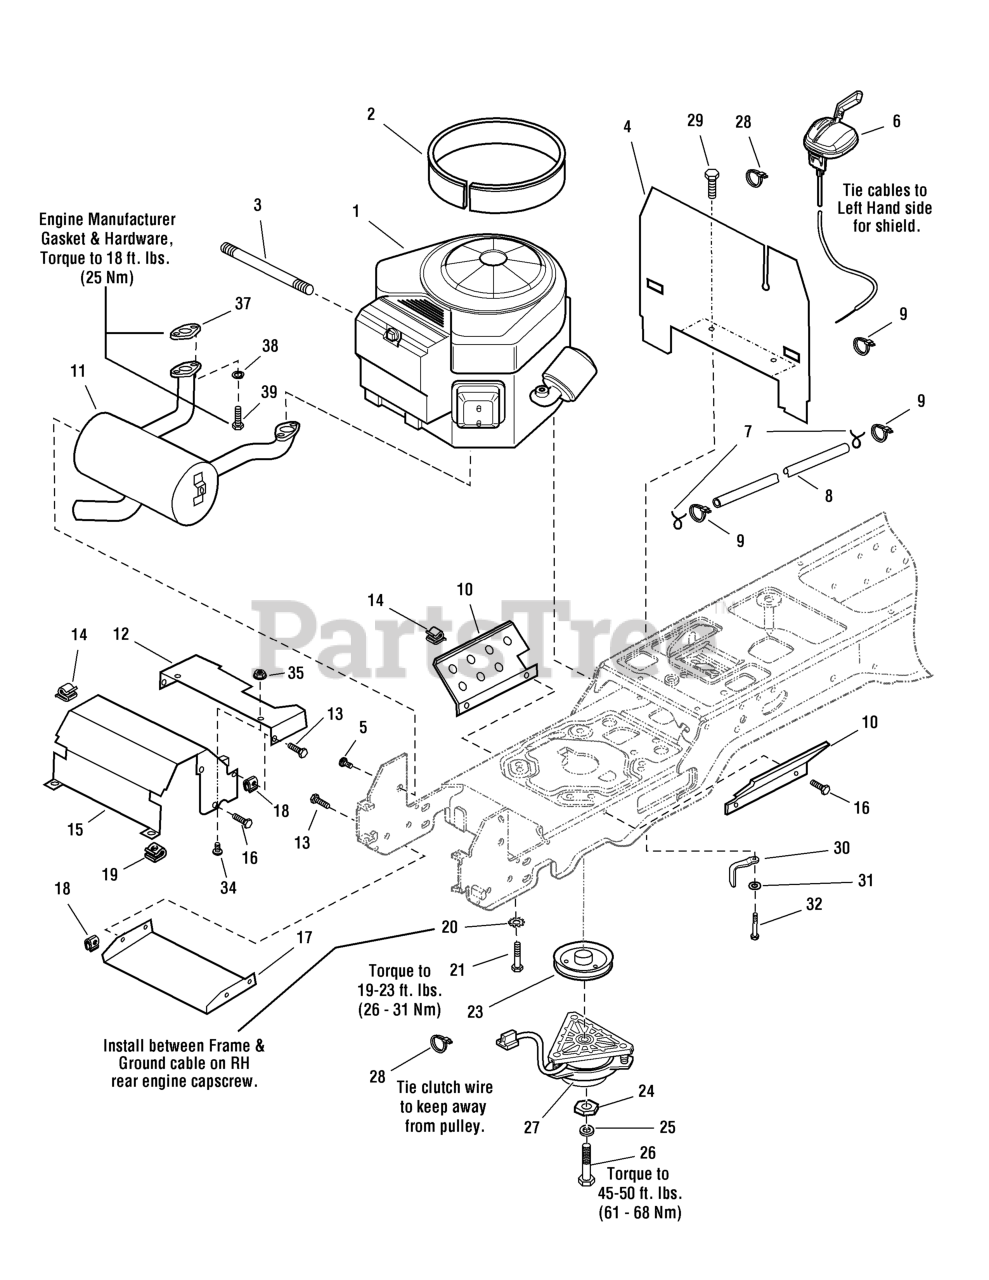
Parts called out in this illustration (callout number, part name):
1	ENGINE, 30 HP Briggs & Stratton
2	EDGING, Airduct
3	HOSE, Oil Drain
4	HEAT SHIELD
5	CAPSCREW, Hex Head, Taptite, 5/16-18 x 1/2
6	THROTTLE CONTROL
7	CLAMP, Hose
8	HOSE, Fuel
9	TIE, Self Locking, 7-5/16 Long
10	SHIELD, Side, Heat
11	MUFFLER ASSEMBLY
12	DUCT, Muffler Extension
13	CAPSCREW, Hex, Whiz Lock, 1/4-20 x 5/8
14	CLIP, Wire
15	DUCT, Muffler Top
16	CAPSCREW, Hex Head Taptite, 1/4-20 x 3/8
17	SHIELD, Muffler Bottom
18	NUT, Speed, 1/4-20
19	NUT, Speed, Lug Type, 5/16-18
20	WASHER, Locking, External Teeth, 3/8
21	CAPSCREW, Hex Head, Taptite, 3/8-16 x 1-1/2
23	PULLEY, Engine
24	WASHER, Hex, 7/16 x 1-1/2
25	WASHER, Locking, 7/16
26	CAPSCREW, Hex Head 7/16-20 x 3-1/2
28	TIE, Self Locking, 3-5/8 Long
29	CAPSCREW, Hex Head Taptite, 1/4-20 x 1/2
30	RETAINER, Clutch
31	WASHER, Flat, 3/8
32	CAPSCREW, Hex Head 3/8-16 x 1
34	SCREW, 1/4-20 X 1/2 ALLEN BH
35	NUT, 1/4-20 Hex Serrated Flange
37	GASKET, Exhaust
38	LOCKWASHER, 5/16
39	CAPSCREW, Socket Head, 5/16-18 x 7/8, G8
